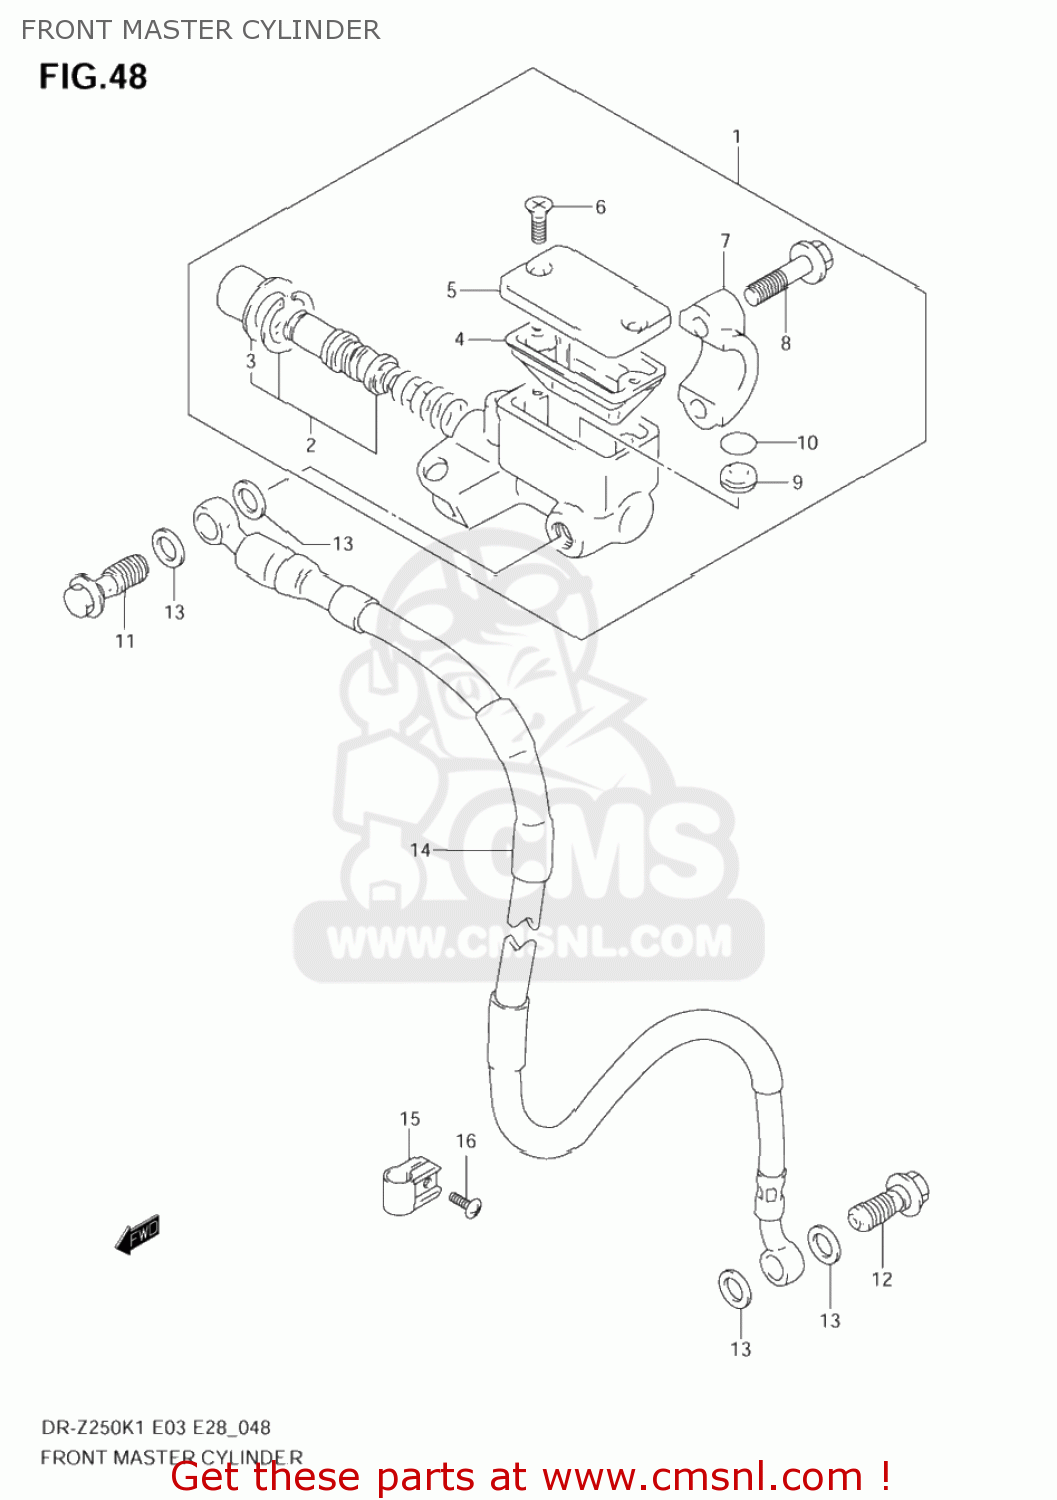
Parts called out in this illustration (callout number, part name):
1	CYLINDER ASSY,FR MASTER
2	PISTON & CUP SET
3	BOOT
4	DIAPHRAGM
5	CAP
6	SCREW
7	HOLDER
8	BOLT
9	SEPARATOR
10	RING
11	BOLT UNION
12	BOLT UNION
13	WASHER(10X15X1.5)
14	HOSE, FRONT BRAKE
15	CLAMP,BRAKE HOSE
16	SCREW
